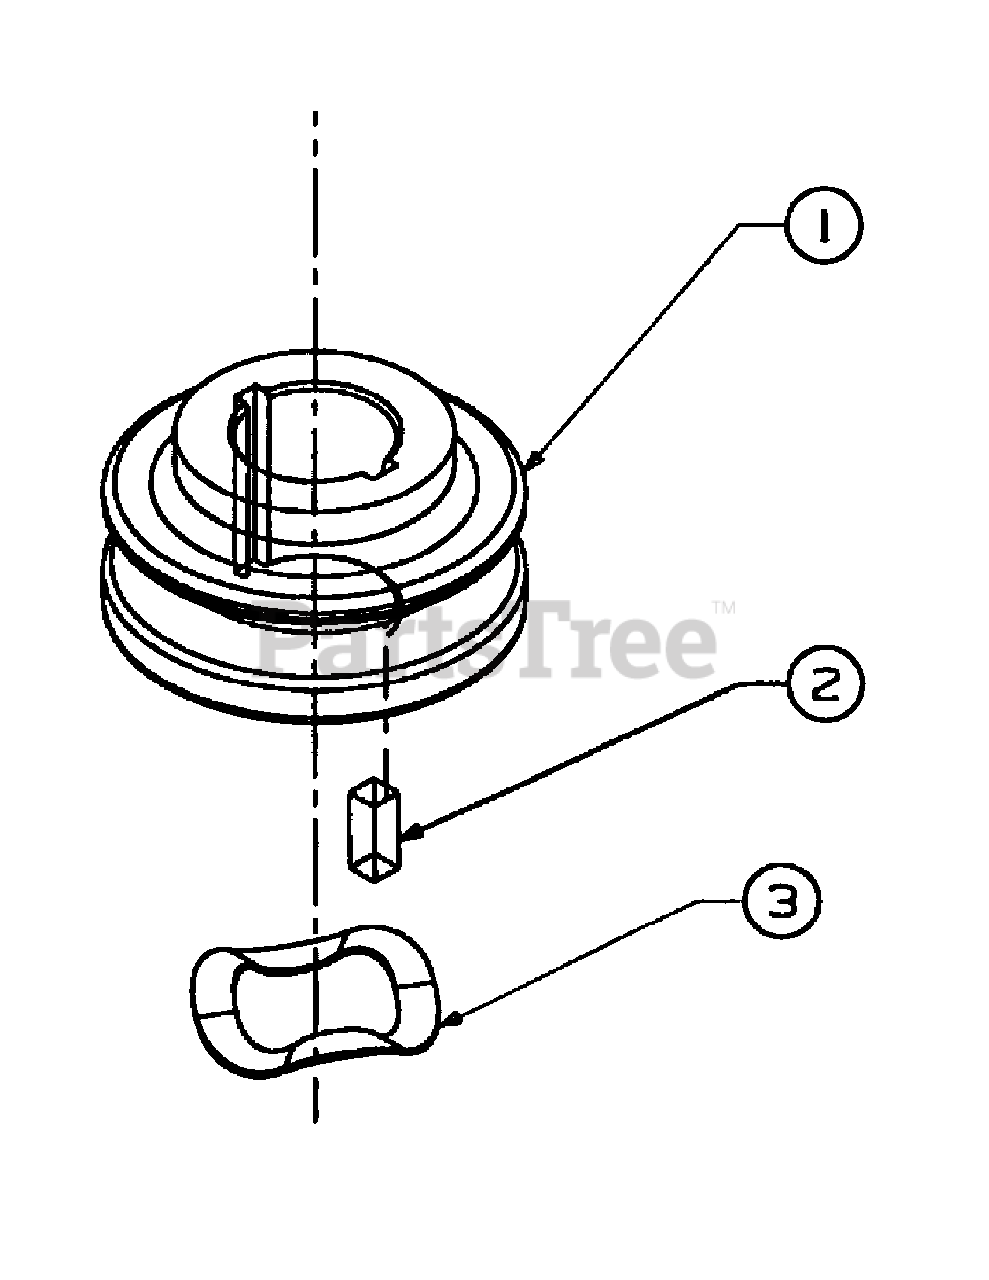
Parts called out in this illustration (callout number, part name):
1	Pulley, Engine
2	Key, Square 3/16
3	Wave Washer
